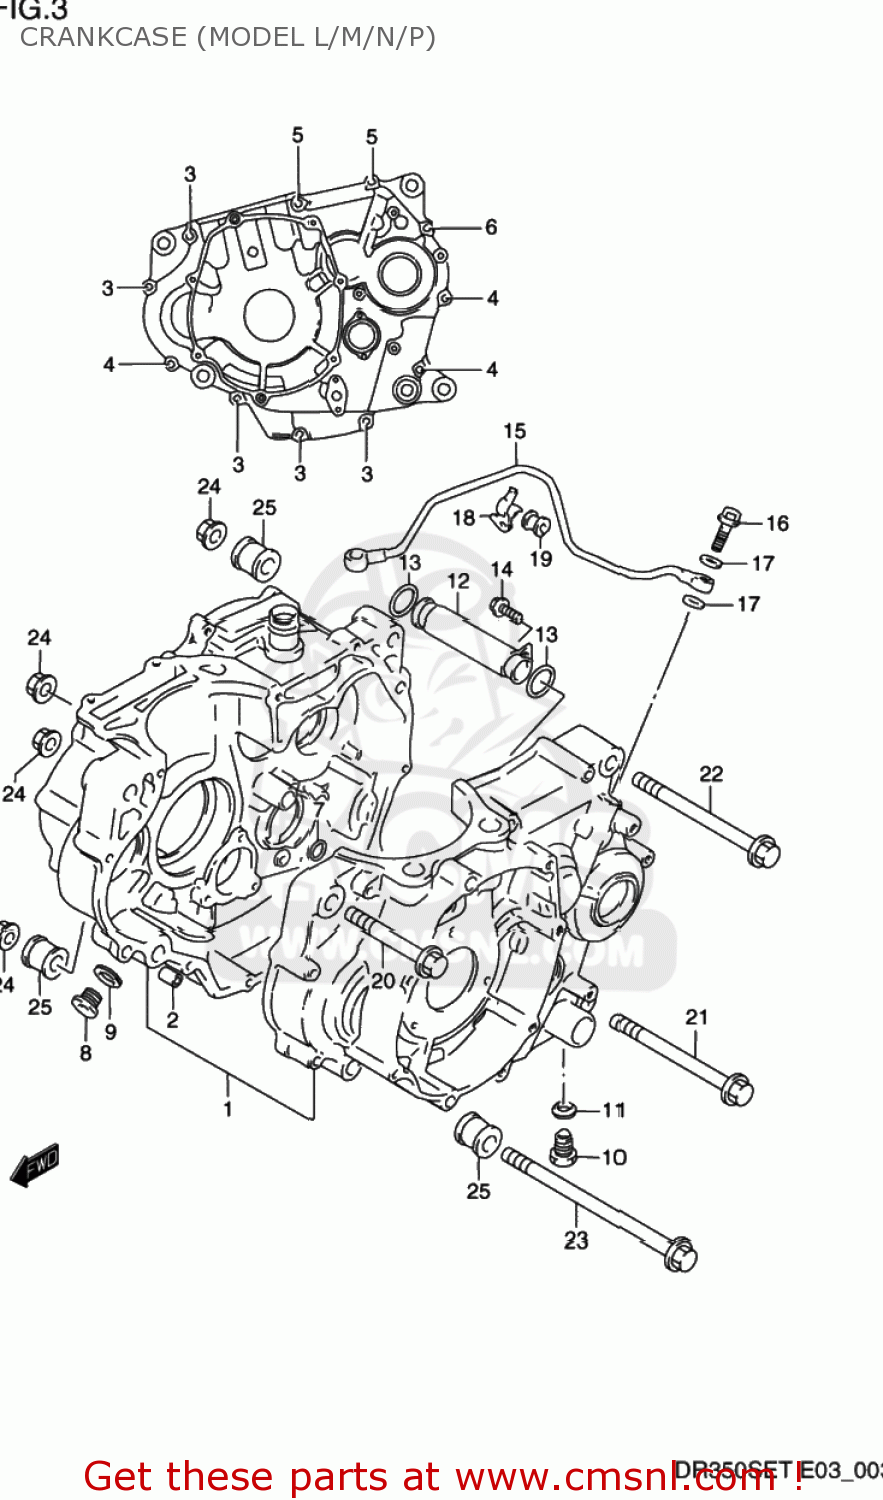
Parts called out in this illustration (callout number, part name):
1	CRANKCASE SET
2	PIN
3	BOLT
4	BOLT
5	BOLT
6	BOLT
7	O-RING
8	PLUG,14X12
9	GASKET(14X19.2X2) (NAS)
10	PLUG,OIL DRN.
11	GASKET(12.1X16.2X3.7) (NAS)
12	PIPE,T/M OIL INNER
13	O RING(D:2.4,ID:15.8)
14	BOLT
15	PIPE,T/M OIL OUTER
16	BOLT UNION
17	GASKET 8.2X14X1 (NAS)
18	CLAMP,OIL PIPE
19	CUSHION
20	BOLT 10X85
21	BOLT(10X101.5)
22	BOLT(10X115)
23	BOLT(10X143)
24	NUT
25	SPACER,ENGINE MOUNT
